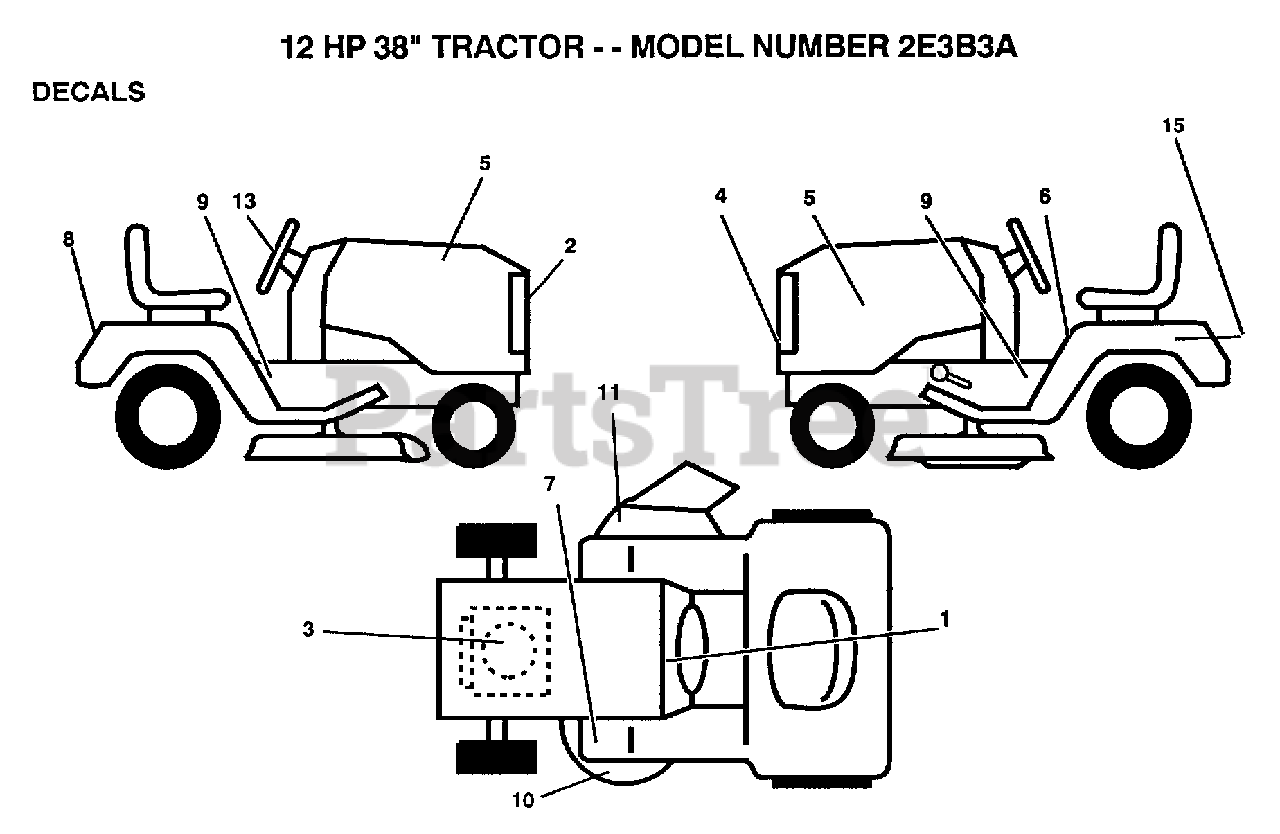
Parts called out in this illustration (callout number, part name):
2	GRILL DECAL
3	DECAL.ENG.271967
5	"DECAL,HOOD"
6	DECAL CAUTION
7	DECAL T
8	FENDER DECAL
11	"DECAL, WARNING"
15	DECAL
